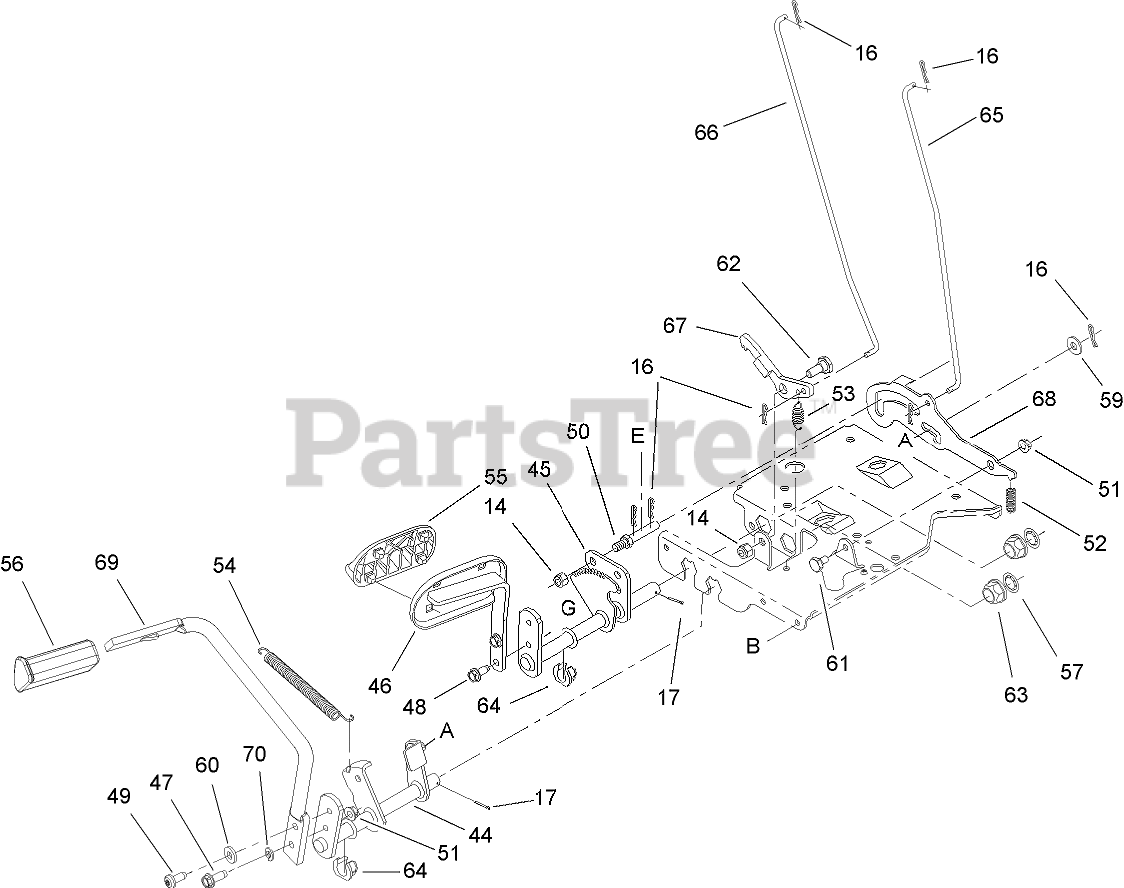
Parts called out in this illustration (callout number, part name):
14	NUT-LOCK, FLANGE
16	PIN-COTTER
17	PIN-COTTER
44	BRAKE CONTROL ASM
45	SPEED CONTROL ASM
46	PEDAL ASM
47	SCREW-HWHTF
48	SCREW-HWH
49	SCREW-TAP
51	NUT-LOCK, FLANGE
52	SPRING
53	SPRING-EXTENSION
54	SPRING-EXTENSION
55	PAD-PEDAL
56	PAD-BRAKE
57	WASHER-FLAT
59	WASHER-FLAT
60	WASHER-FLAT
61	BOLT-SHOULDER
62	BOLT-SHOULDER
63	BEARING-FLANGE
64	BEARING-FLANGE, HEX (SPLIT)
65	ROD-BRAKE, LOCK CONTROL
66	ROD-CONTROL, CRUISE
67	LATCH-CRUISE
68	BRACKET-LOCK OUT
69	PEDAL-BRAKE
70	WASHER-LOCK
